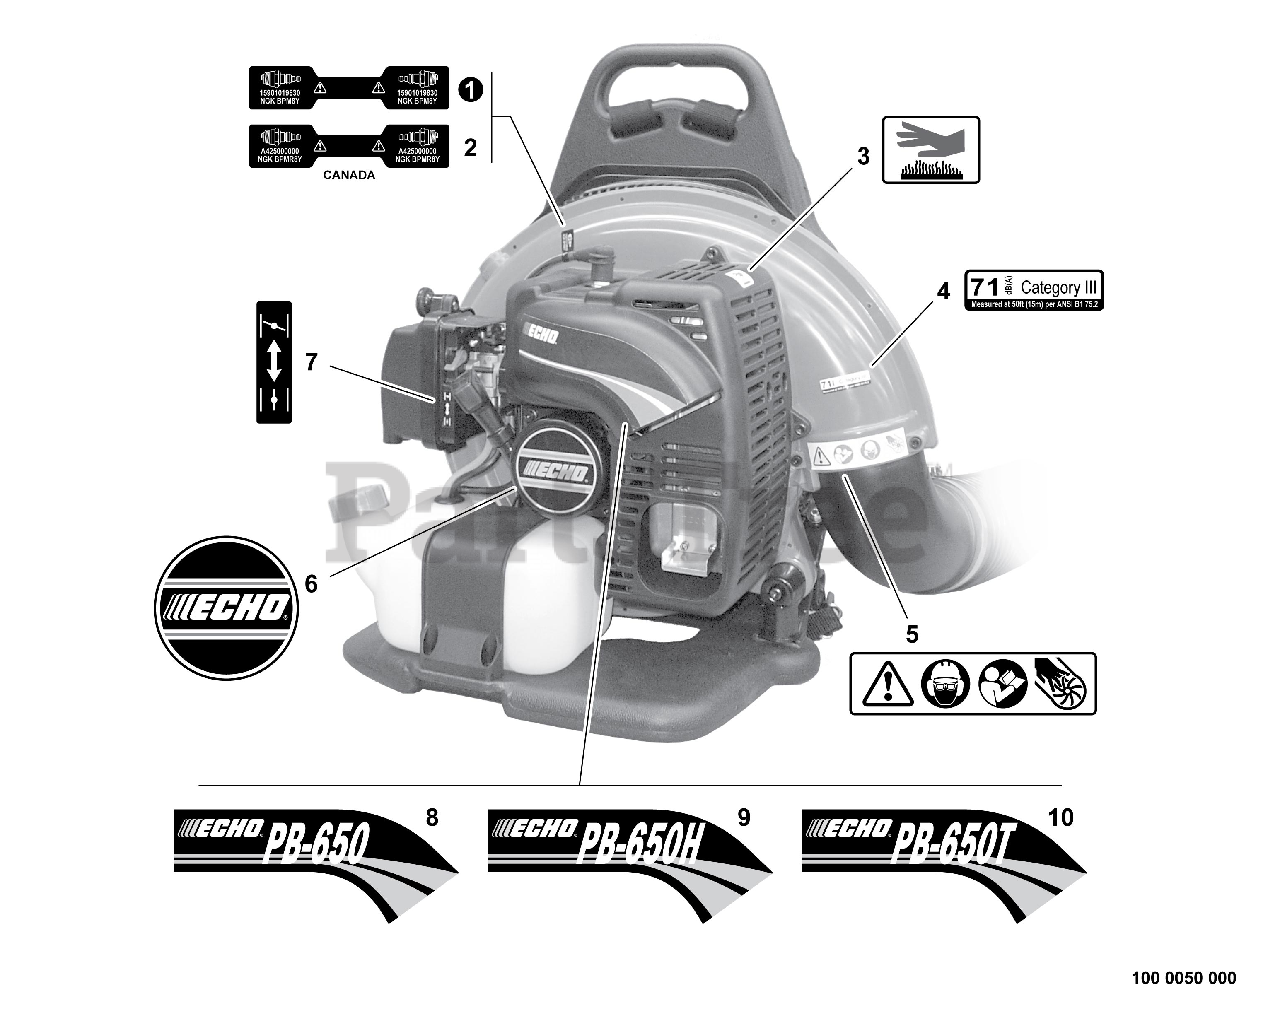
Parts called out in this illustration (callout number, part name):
1	LABEL - SPARK PLUG -- BPM-8Y
2	LABEL - SPARK PLUG -- BPMR-8Y
3	LABEL - HOT SURFACE
4	LABEL - NOISE 71dB(A) CAT III
5	LABEL - CAUTION
6	LABEL - ECHO
7	LABEL - CHOKE
8	LABEL - MODEL PB-650
9	LABEL - MODEL PB-650H
10	LABEL - MODEL PB-650T
